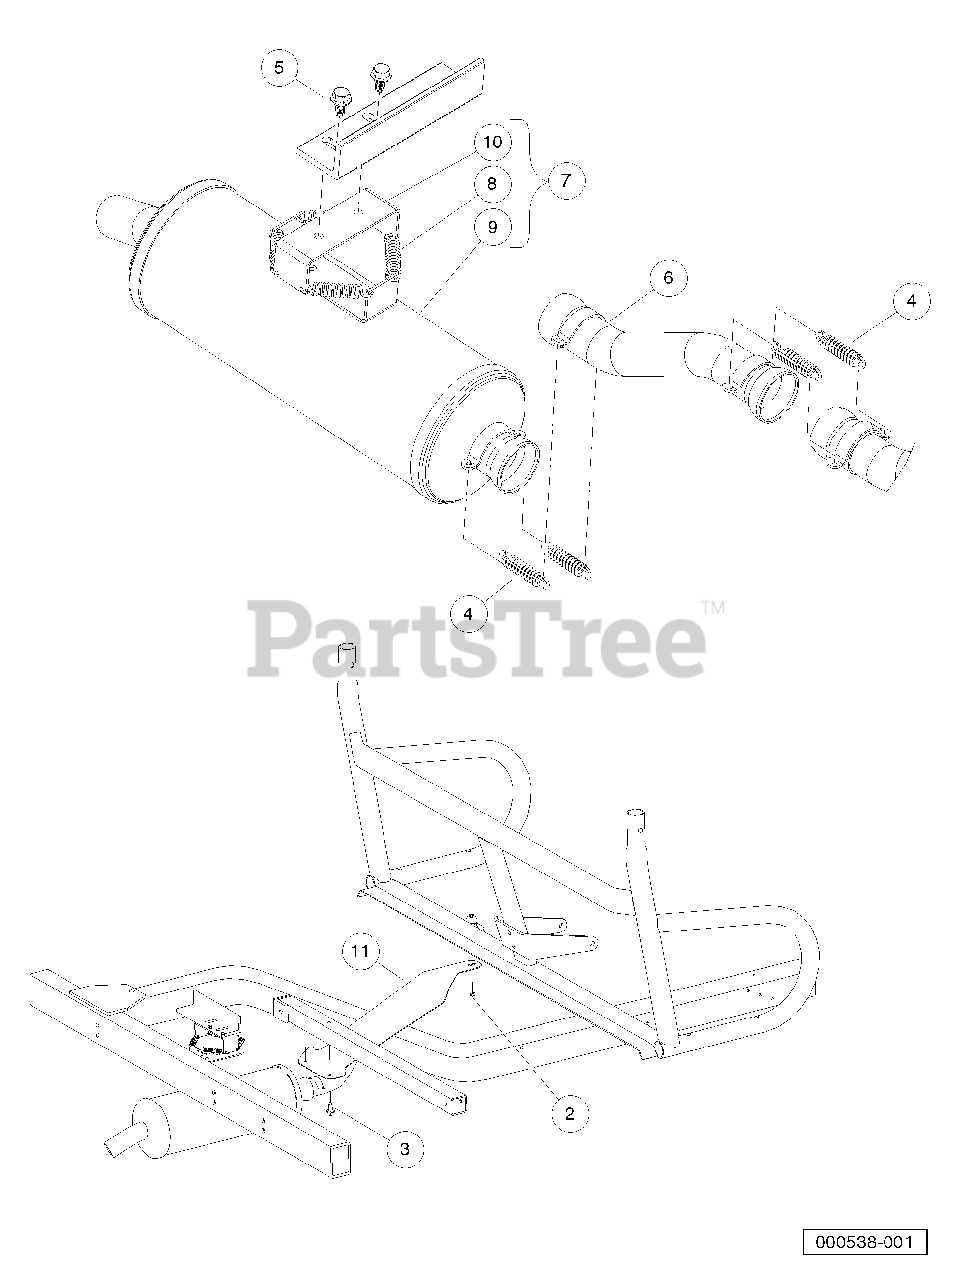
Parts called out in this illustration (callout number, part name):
1	Instl, Exhaust, AWD
2	Locknut, M6-1.00 Nylon Insert
3	M8-1.25x20 Taptite
4	Spring, Exhaust
5	Bolt Flanged Head, M8 X1.25x 16 with Loctite
6	Pipe, Exhaust, Int, Offset
7	Asm, Muffler, AWD Homologation
8	Spring, Exhaust
9	Muffler
10	Bracket, Muffler
11	Shield, Exhaust, Clearance
